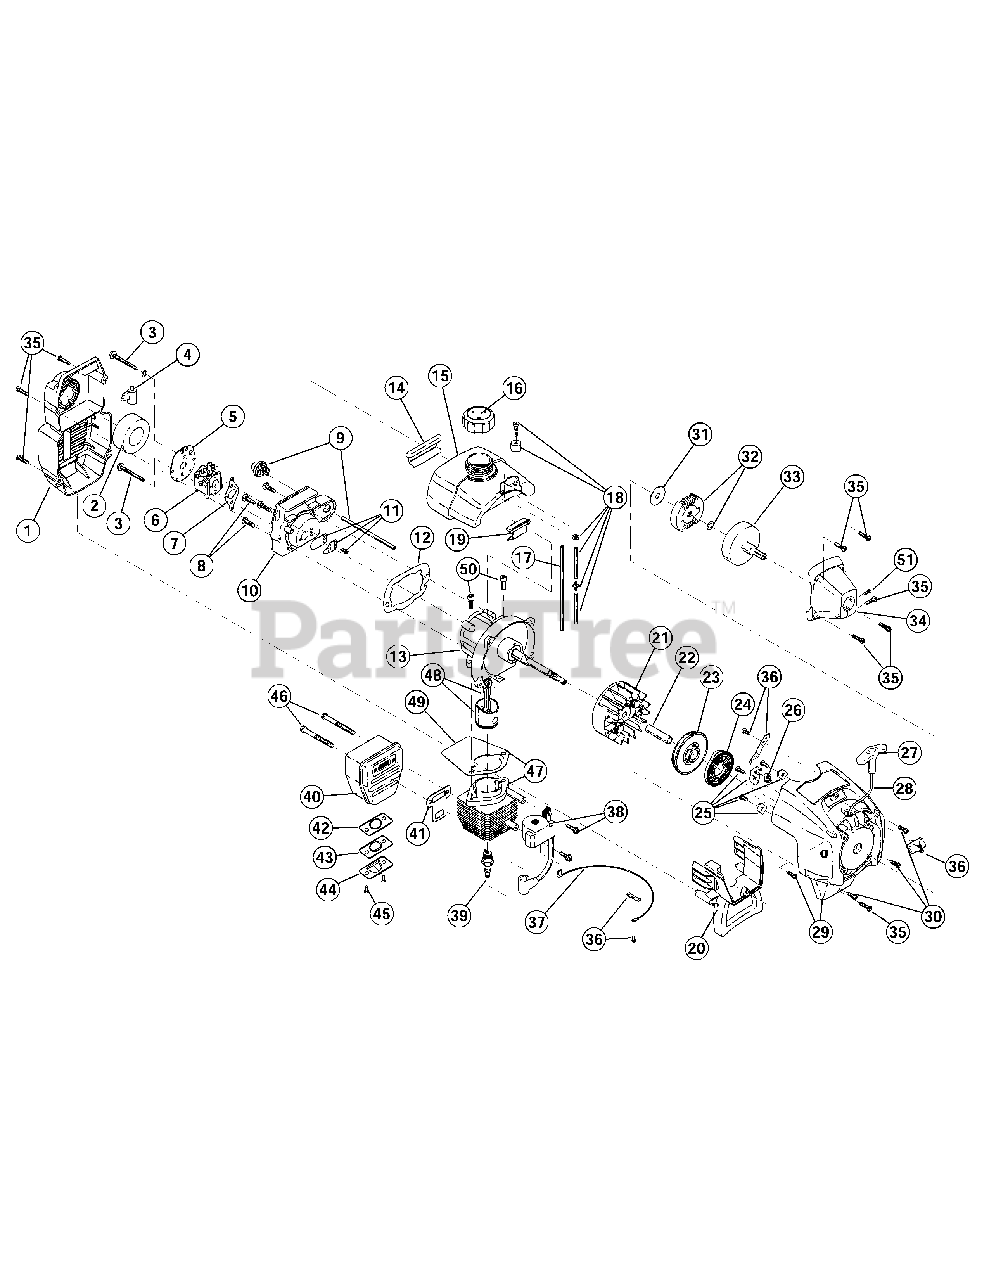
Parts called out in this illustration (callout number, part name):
1	Air Cleaner Cover Assembly (includes 2 & 35)
2	Air Cleaner Filter
3	Carburetor Mounting Screw Assembly
4	Choke Lever
5	Choke Plate
6	Carburetor Assembly (includes 7 & 18)
7	Carburetor Gasket
8	Carb Mount Screw
9	Primer and Hose Assembly
10	Carb Mount Assembly (includes 8,11 & 12)
11	Reed Assembly
12	Carburetor Mount Gasket
13	Crank Case Service Assembly (includes 8)
14	Rear Mounting Pad
15	Fuel Tank Assembly (includes 16-18)
16	Fuel Cap Assembly
17	Fuel Return Line
18	Fuel Line Assembly
19	Front Mounting Pad
20	Shroud Extension & Stand (includes 35)
21	Flywheel Assembly
23	Recoil Pulley Assembly
24	Recoil Spring
25	Pulley Retainer Assembly
27	Pull Handle
29	Starter Housing Assembly (includes 23-28, 30, & 35-37)
30	Housing Screw
31	Clutch Washer
32	Clutch Rotor Assembly
33	Clutch Drum Assembly
34	Clutch Cover Assembly (includes 35 & 48)
36	Switch Assembly
37	Wire Lead
38	Module Assembly
40	Muffler Assembly (includes 41-43)
41	Exhaust Gasket
42	Spark Arrestor Screen
43	Exhaust Diverter Hood
44	Exhaust Diverter
45	Screw
46	Muffler Mounting Bolt Assembly
47	Cylinder Assembly (includes 46 & 47)
48	Piston and Rod Assembly
49	Cylinder Gasket
50	Cylinder Bolt
51	Anti-Rotation Screw
